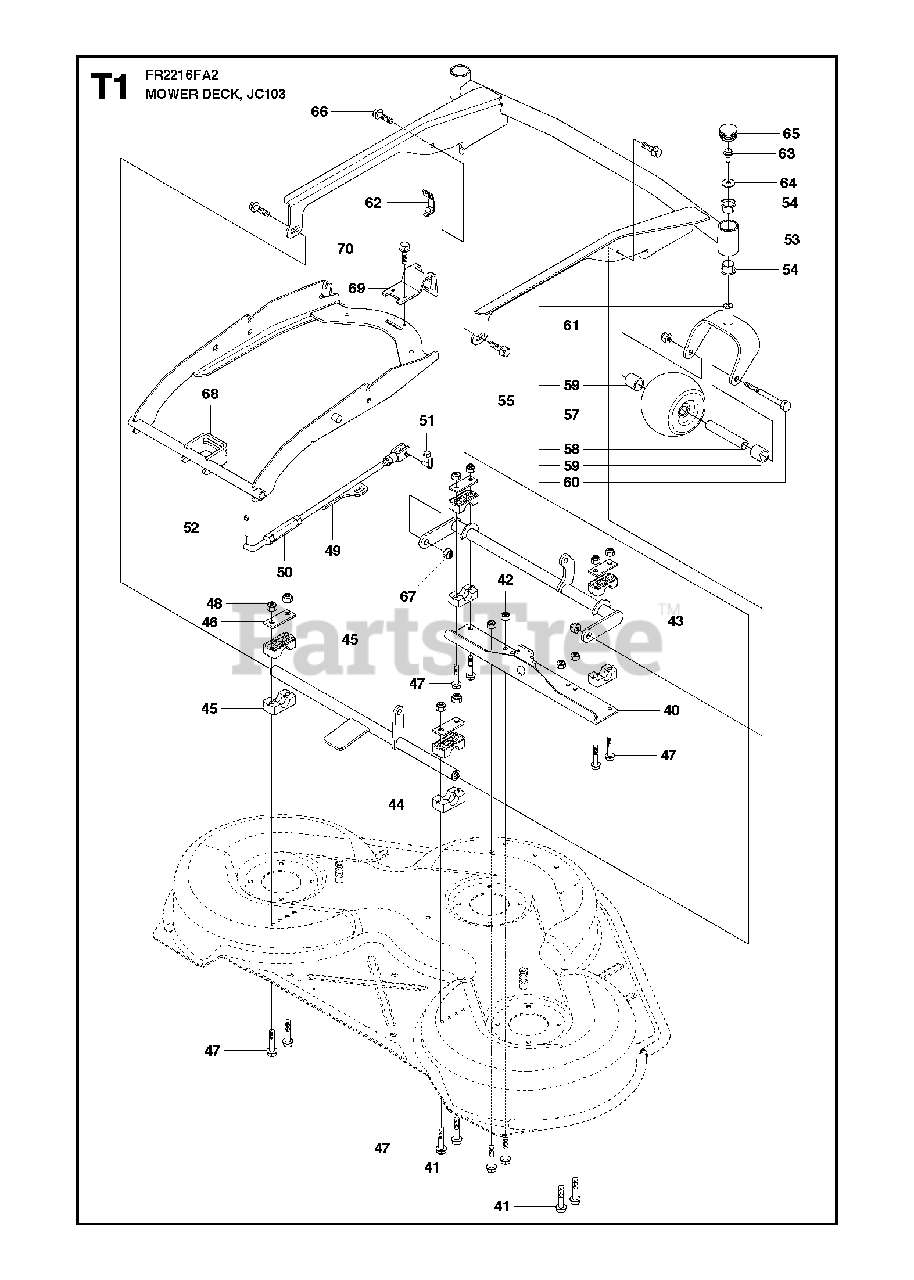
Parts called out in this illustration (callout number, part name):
42	LOCKNUT M8
48	LOCKNUT M8
49	PARALLELL ROD ASSY
50	PARALLEL ROD
51	RETAINER
52	SPLIT PIN
57	DECK ROLLER, FRONT
58	PIPE
59	SPACER
61	NUT
66	SCREW
67	LOCKNUT M8
70	SCREW
